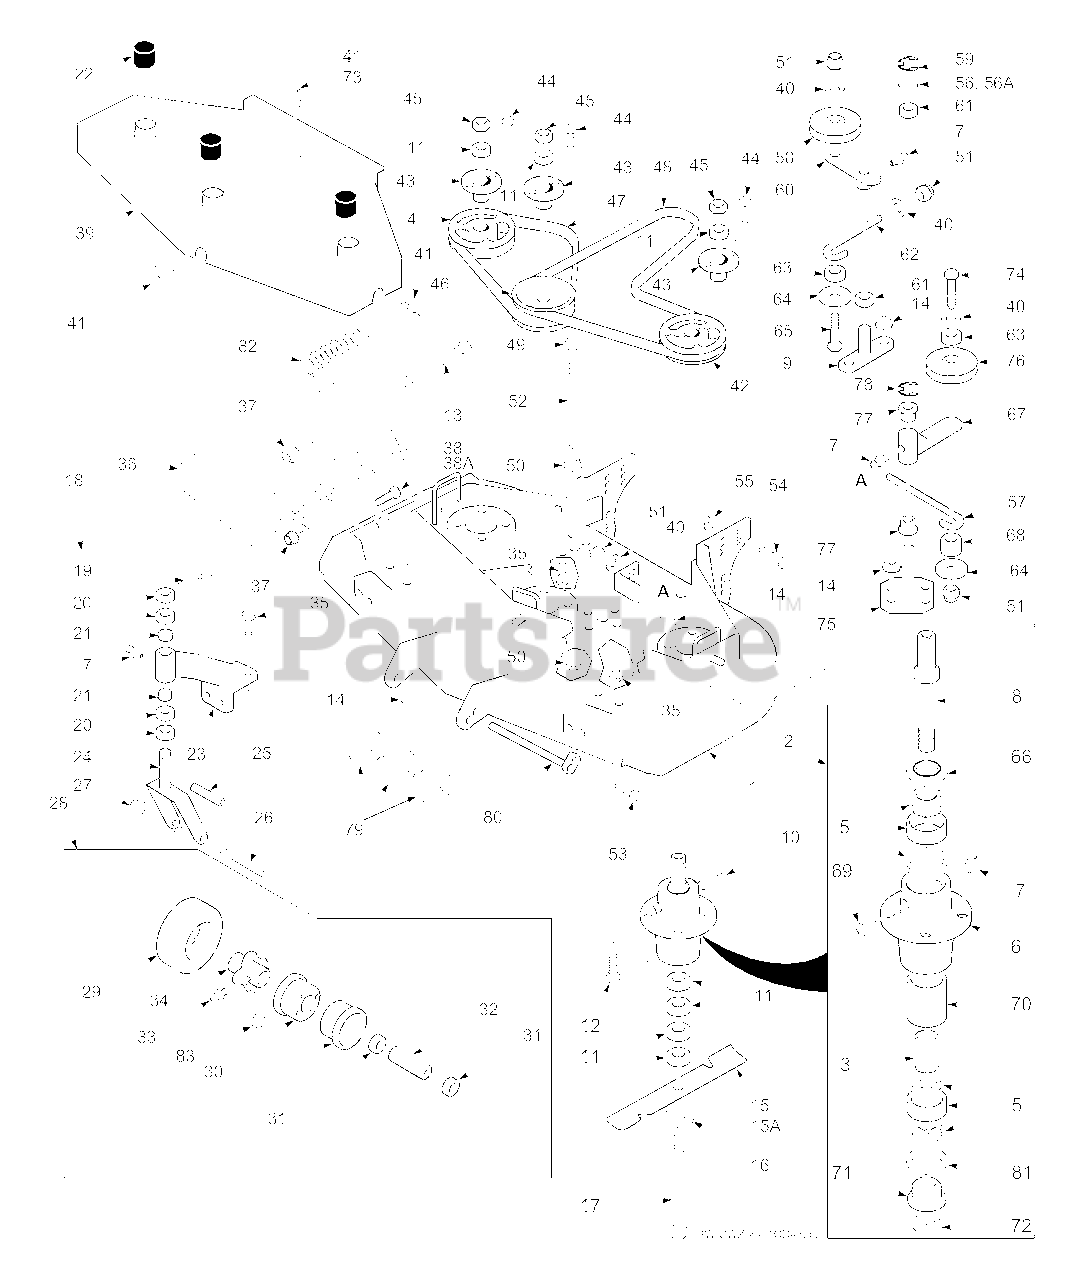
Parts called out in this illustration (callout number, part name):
1	Cutter Deck
2	Spindle Assembly
3	Spacer, Inside
4	Pulley
5	Tapered Bearing (Two)
6	Spindle Housing
7	Grease Fitting Str. 5/16"
8	Spindle Shaft, Tapered Brng
9	Idler Pivot
10	Key, 1/4 x 1/4 x 2"
11	Spacer, Cutter Blade - Small
12	Bolt, 5/16-18 x 1-1/4" Hex Head
13	Bolt, 5/16-18 x 4-3/4" Hex Head
14	Serrated Flange Nut, 5/16-18
15	Cutter Blade 16-1/2" Marbain
15A	Cutter Blade High Lift Marbain
16	Flatwasher, 5/8" (.688 x 1.75 x .134)
17	Hex Head Bolt, 5/8-11 x 9-1/2"
18	Caster Assembly,
19	Quick Pin
20	Spacer, Caster Yoke, 1/2" thick
21	Bronze Bearing
22	Spindle Shield
23	Support Assembly,
24	Caster Yoke
25	Sleeve, Caster Wheel Bearing
26	Hex Hd Bolt, 1/2-13 x 5-1/2"
27	Elastic Stop Nut, 1/2-13
28	Wheel Assy.
29	Tire only, Caster Wheel
30	Rim Pair, Caster Wheel
31	Bearing Retainer, Caster Wheel
32	Roller Bearing, Caster Wheel
33	Grease Fitting 45 deg., 1/4-28
34	Hub Assembly,
35	Capscrew, 5/16-18 x 3/4"
36	Discharge Chute
37	Nut, 5/16-18 Elastic Elastic Stop
38	Bolt, 5/16-18 x 1-1/2" Hex Head (Front)
38A	Bolt, 5/16-18 x 1-3/4" Hex Head (Rear)
39	Belt Cover
40	Flat Washer, 3/8" Special
41	Wing Nut, 3/8-16 (Large)
42	Pulley
43	Tapered Hub
44	Bolt, 1/4-20 x 3/4" Hex Head
45	Nut, 5/8-11 Hex
46	Pulley, Double
47	Belt, RH Blade Drive
48	Belt, Blade Drive
49	Nut, 3/8-16, Nut Centerlock
50	Nut, 3/8-16, Serrated Flange
51	Nut, 3/8-16 Elastic Stop
52	Support, Belt Cover
53	Bolt, 5/16-18 x 1/2" Hex Head
54	Cpscrw,7/16-14 x 1" Ser Flng Hex Hd
55	Nut, 7/16-14 Serrated Flange
56	Flat Washer 3/4" Special
56A	Flat Washer 3/4" Special
57	J-Hook
58	Idler Pulley, "V" Groove
59	Retaining Ring, 3/4" Ext."E"
60	Idler Arm Assy.
61	Bronze Bearing
62	J-Rod, Idler Pulley
63	Spacer, J-Rod
64	Washer, 3/8 x 1-1/2 x 16 ga.
65	Bolt, 3/8-16 x 2-1/4" Hex Head
66	Seal, Cutter Spindle
67	Idler Arm Assy
68	Spacer, J-Rod
69	Relief Fitting, Cutter Spindle
70	Spacer, Outside, Cutter Spindle
71	Spindle Bushing
72	Nut, Cutter Spindle
73	Wing Nut, 3/8-16 (Small) Top Side
74	Bolt, 3/8-16 x 3-1/2" Hex Head
75	Idler Pivot
76	Idler Pulley, Belt Clutch
77	Bronze Bearing
78	Retaining Ring
79	Guide Roller
80	Roller Shaft
81	Seal, Cutter Spindle
82	Spring, Chute Return
83	Nut, 3/8-24 Tapered
